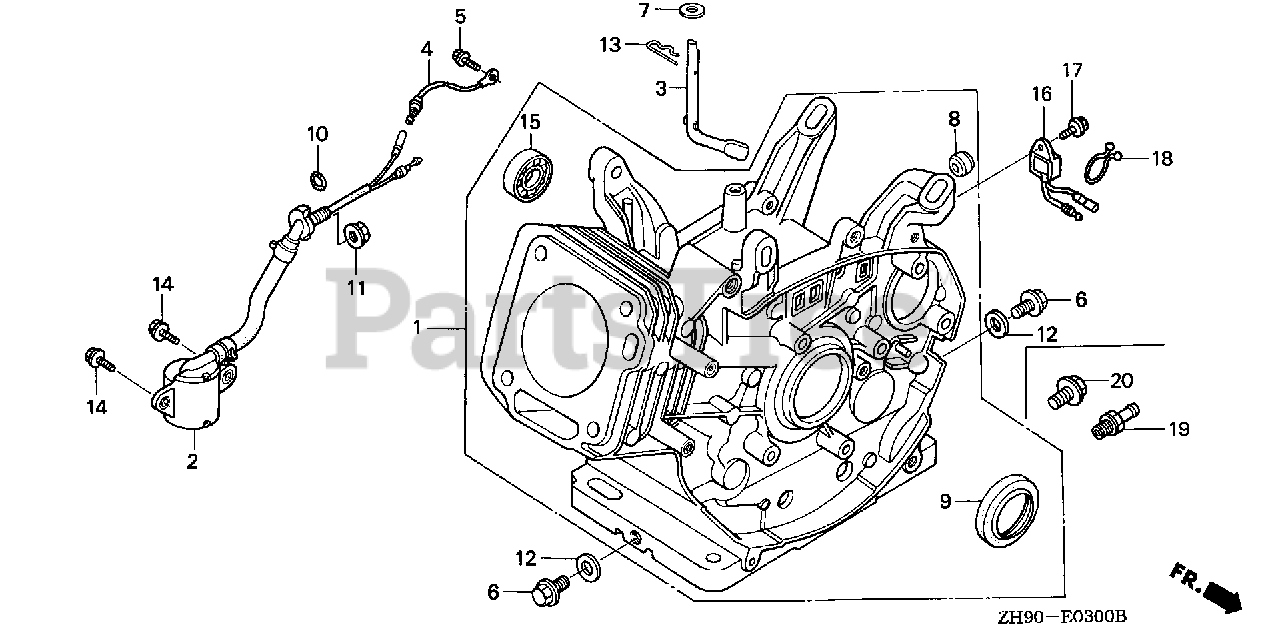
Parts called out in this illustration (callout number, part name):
1	CYLINDER ASSY. (BALANCER+SELFSTARTER+ALERT)
1	CYLINDER ASSY.
2	SWITCH ASSY., OIL LEVEL
3	SHAFT, GOVERNOR ARM
6	BOLT, DRAIN PLUG
7	WASHER (8.2X17X0.8)
9	OIL SEAL (30X46X8)
10	O-RING (14MM) (ARAI) Use up to Engine SN 2949254.
10	O-RING (14MM) (NOK)
11	NUT, FLANGE (10MM)
12	WASHER, DRAIN PLUG (12MM)
13	PIN, LOCK (10MM)
14	BOLT, FLANGE (6X12) Use up to Engine SN 1543277.
15	BEARING, RADIAL BALL (6202)
